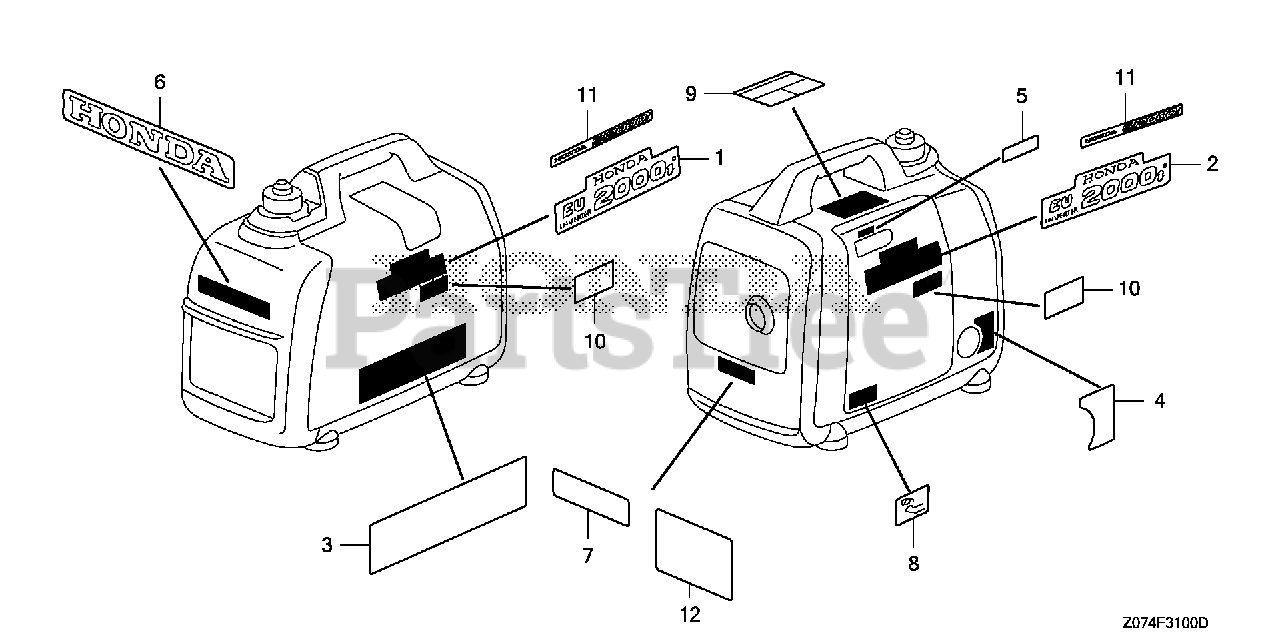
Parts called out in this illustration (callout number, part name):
3	MARK, CAUTION
4	MARK, ENGINE SWITCH
5	MARK, CHOKE
6	MARK, HONDA
7	MARK, EX. CAUTION
8	MARK, OIL CAUTION
9	MARK, CPSC (CO CAUTION)
11	MARK, EMBLEM
12	MARK, EX. WARNING (E)
